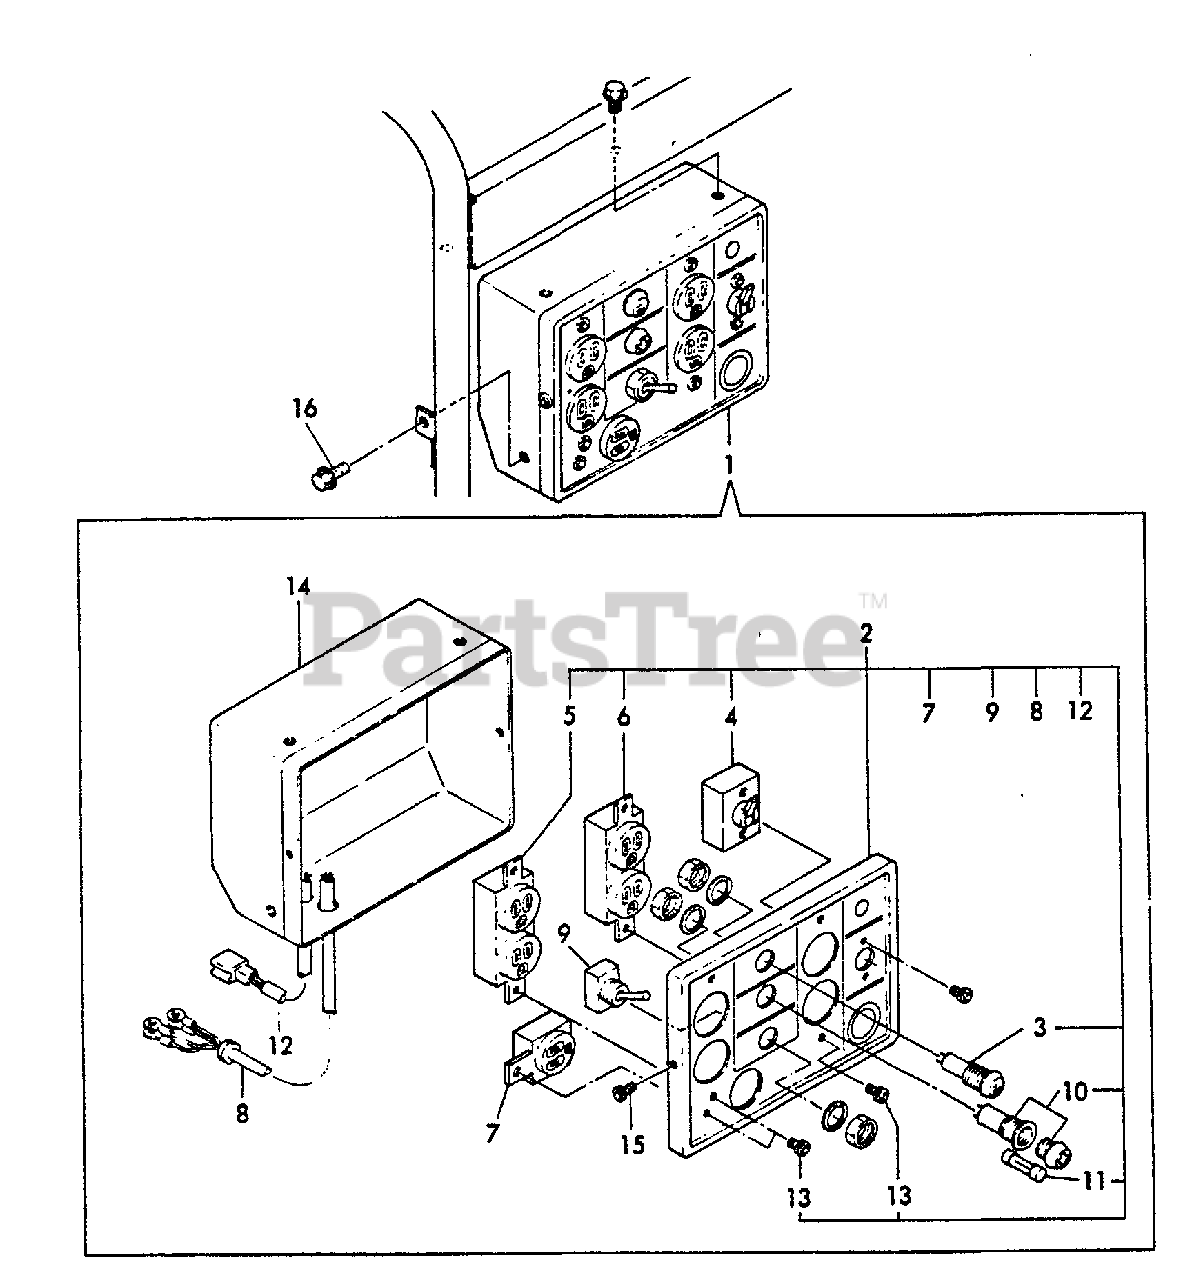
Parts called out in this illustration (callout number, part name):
1	PANEL BOX ASSY
2	PANEL ASSY
3	LAMP, PILOT - 100V
4	BREAKER - 15A
5	AC CONNECT
6	PLUG SOCKET 240V
7	PLUG SOCKET 120V
8	WIRE HARNESS
9	SWITCH
10	HOLDER, FUSE
11	FUSE - 20A
12	DIODE
13	SCREW - 4×8
14	BOX, PANEL
15	SCREW - 4×8
16	BOLT - 6×8 -- PLATED
